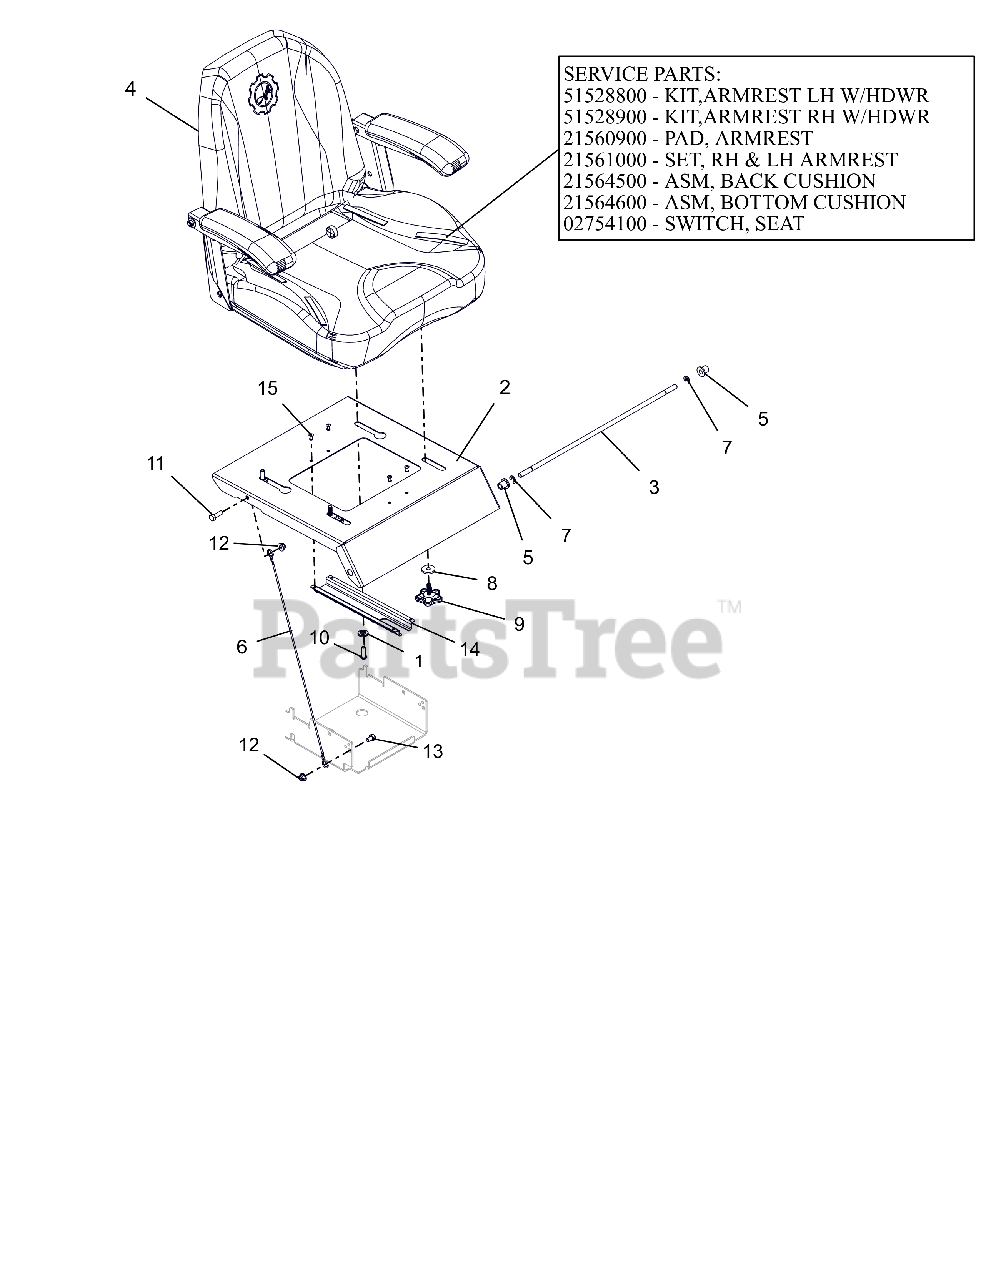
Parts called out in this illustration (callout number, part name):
1	BSHG, FLG .312X.499X.23X.88
2	PLATE, SEAT (FASTENER SLIDE)
3	ROD, SEAT PIVOT
4	SEAT, IKON
4	KIT, ARMREST LH
4	KIT, ARMREST RH
4	PAD, ARMREST (HARD)
4	SET,RH & LH ARMREST -HARD
4	ASM, BACK CUSHION-ARIENS X
4	ASM, BOTTOM CUSHION-ARIENS X
4	SWITCH- SNAP MTG N.O.
5	BSHG-FLG .38X.580X.667X.750
6	LANYARD, SEAT CABLE .093X19.5
7	RG-RTNG-EXT .375X.035 TYP E
8	WSHR, FLT .340X1.125X.135 ZCC
9	KNOB, WING STUDDED
10	BLT,SHCS-BTN .31-18X1.00 ZCC
11	BLT,HEX .31-18X1.00 G5 ZCC
12	NUT,LK-NYL-FLG .31-18 G5ZC120
13	BLT, HEX .31-18X.50 GR5 ZCC
14	GUARD, SEAT SWITCH (GREY PEARL)
15	RVT-POP.187X.527 DOME ST
